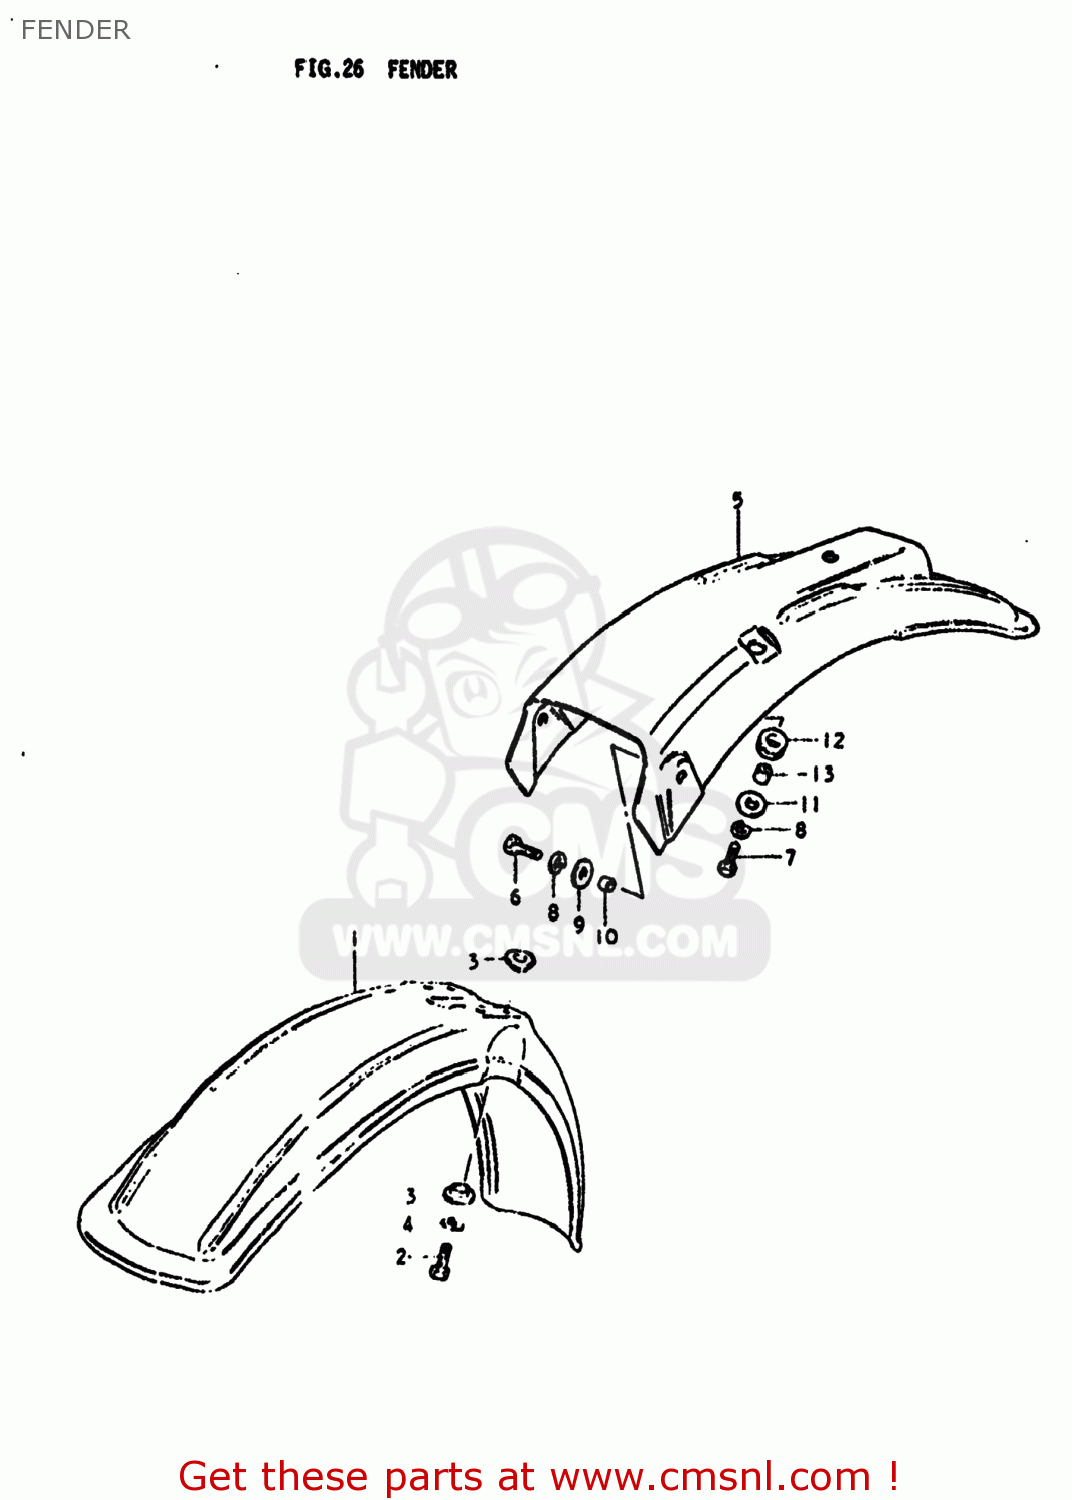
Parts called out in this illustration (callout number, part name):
1	FENDER,FRONT
2	BOLT, UPPER
3	SPACER
4	LOCK WASHER
5	FENDER,REAR
6	BOLT, UPPER
7	BOLT
8	LOCK WASHER
9	WASHER
10	SPACER (6.1X8X5.2)
11	WASHER (6.5X24X1.6)
12	CUSHION
13	SPACER
